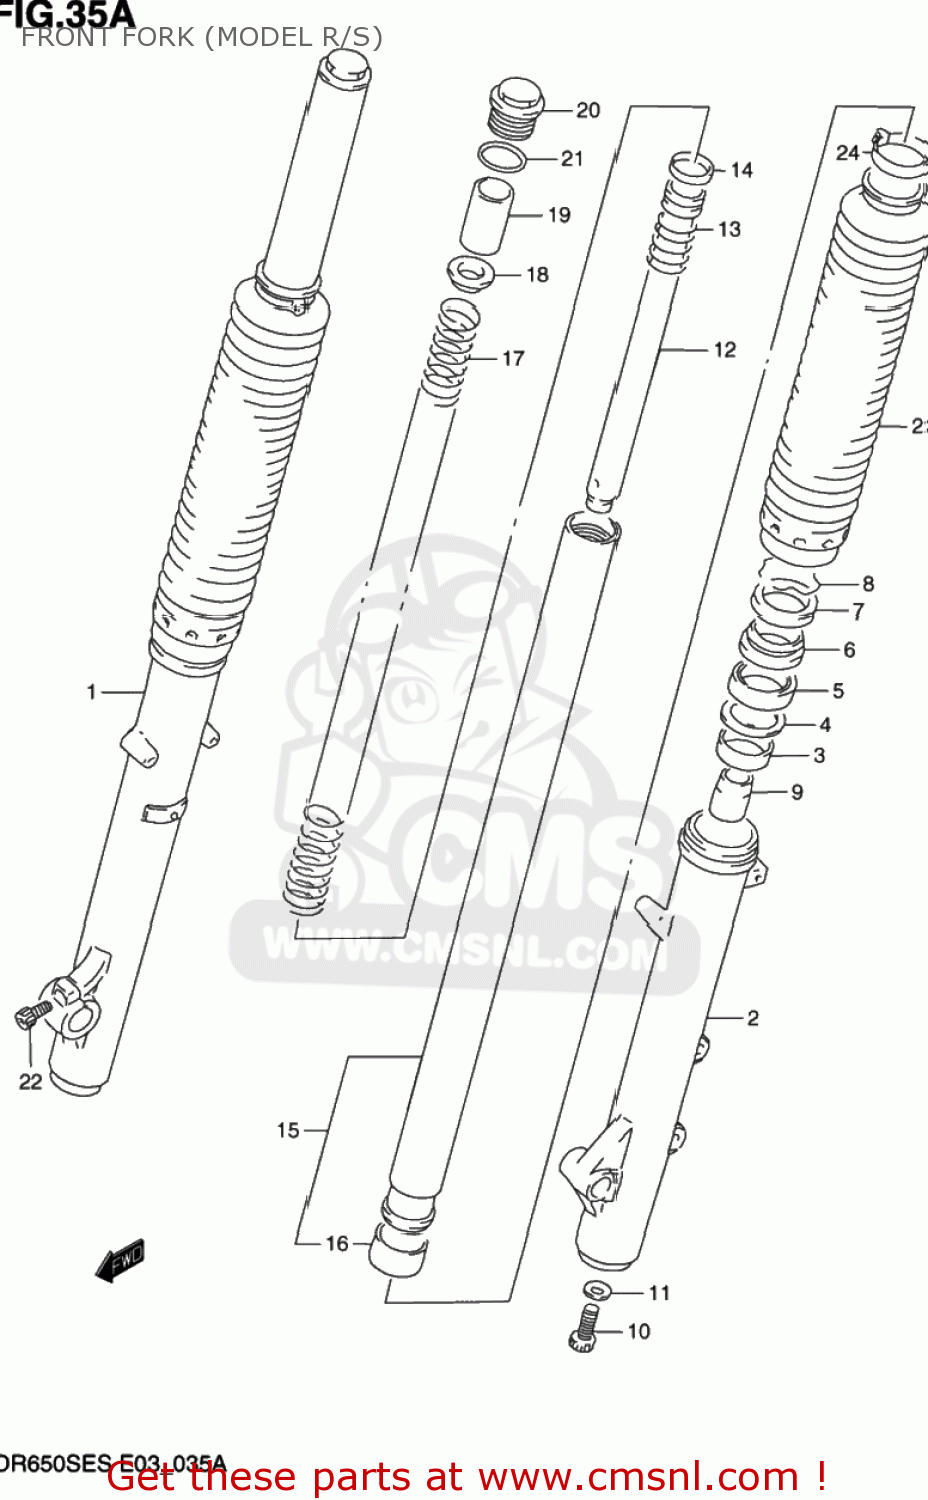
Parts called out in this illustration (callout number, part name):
1	TUBE,OUTER,R
2	TUBE,OUTER,L
3	METAL,SLIDE
4	WASHER,FORK OIL SEAL
5	SEAL,OIL
6	SEAL,DUST
7	WASHER
8	RING,OIL SEAL STOPPER
9	PIECE,OIL LOCK
10	BOLT(14X25)
11	GASKET (NAS)
12	CYLINDER
13	SPRING,REBOUND
14	RING,FR FORK PISTON
15	TUBE,INNER
16	PISTON
17	SPRING,MAIN
18	GUIDE,SPRING
19	SPACER,SPRING
20	CAP,FORK
21	O RING(D:3.5,ID:31.7)
22	BOLT,SOCKET HEAD(8X22)
23	BOOT(BLUE)
24	BAND,BOOT
